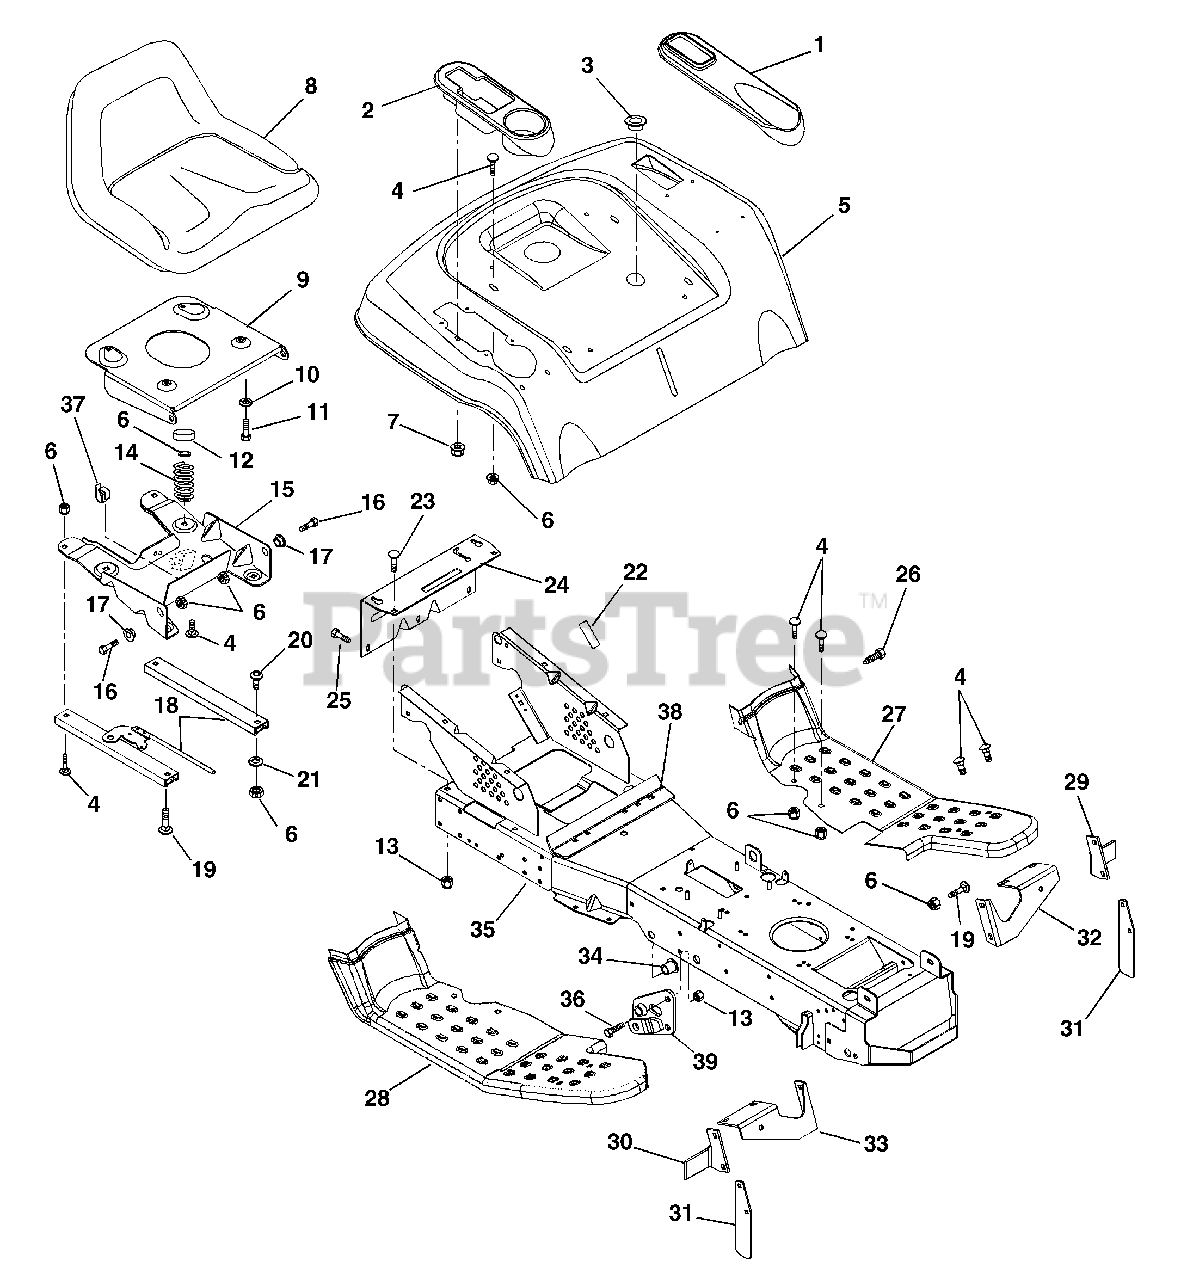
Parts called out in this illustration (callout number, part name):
1	INSERT- LIFT
2	INSERT - BEVERAGE
3	SNAP BUSHING
4	@BLT-RHDSSQNK .31-18X.62 G5YZ
5	REAR DECK
6	@NUT-LK-TOP-FLG .31-18 YWZC
7	NUT-SELF-THRDNG FITS.25 STUDPL
8	SEAT- V1400
9	SEAT PIVOT PLATE
10	WSHR-LK .312X.097 HVY YWZC
11	@BLT-HEX .31-18X.75 GR5 YWZC
12	TUBE CAP
13	@NUT-LK-TOP-FLG .38-16 YWZC
14	SG-COMP .148X1.23X2.41 WLD87
15	BOX, SEAT
16	@BLT-HEX .31-18X.75 GR5 YWZC
17	BSHG-FLG .325X.465X.333X.685
18	SEAT SLIDES -(RAME TAK-3010-4)
19	@BLT-RHDSSQNK .31-18X.62 G5YZ
20	SCR-CAP BTHD.31-18X.50 GR5 YZ
21	WSHR-LK-INT .313X.030 PL
22	PAD,BATTERY
23	@BLT-RDHDSQNK .38-16X.75 G2YWZ
24	DRAW BAR
25	@SCR-TAP .31-18X.75 HWH TR YWZ
26	@SCR-TAP .31-18X.50 HWH TR YWZ
27	FOOT REST L.H.
28	FOOT REST R.H.
29	LIMITER, MOWER HEIGHT (LH)
30	LIMITER, MOWER HEIGHT (RH)
31	BRACKET, DECK STOP
32	BRACE - FOOT REST L.H.
33	BRACE - FOOT REST R.H.
34	BSHG-FLG .515X.750X.745X1.00NY
35	FRAME, MAIN (WELDMENT)
36	@BLT-HEX .38-16X.75 GR5 YWZC
37	CLIP-HARNESS TINNERMAN
38	PLATE, FRAME-REINFORCING
39	WELDMENT, LIFT LINK MOUNT RH
